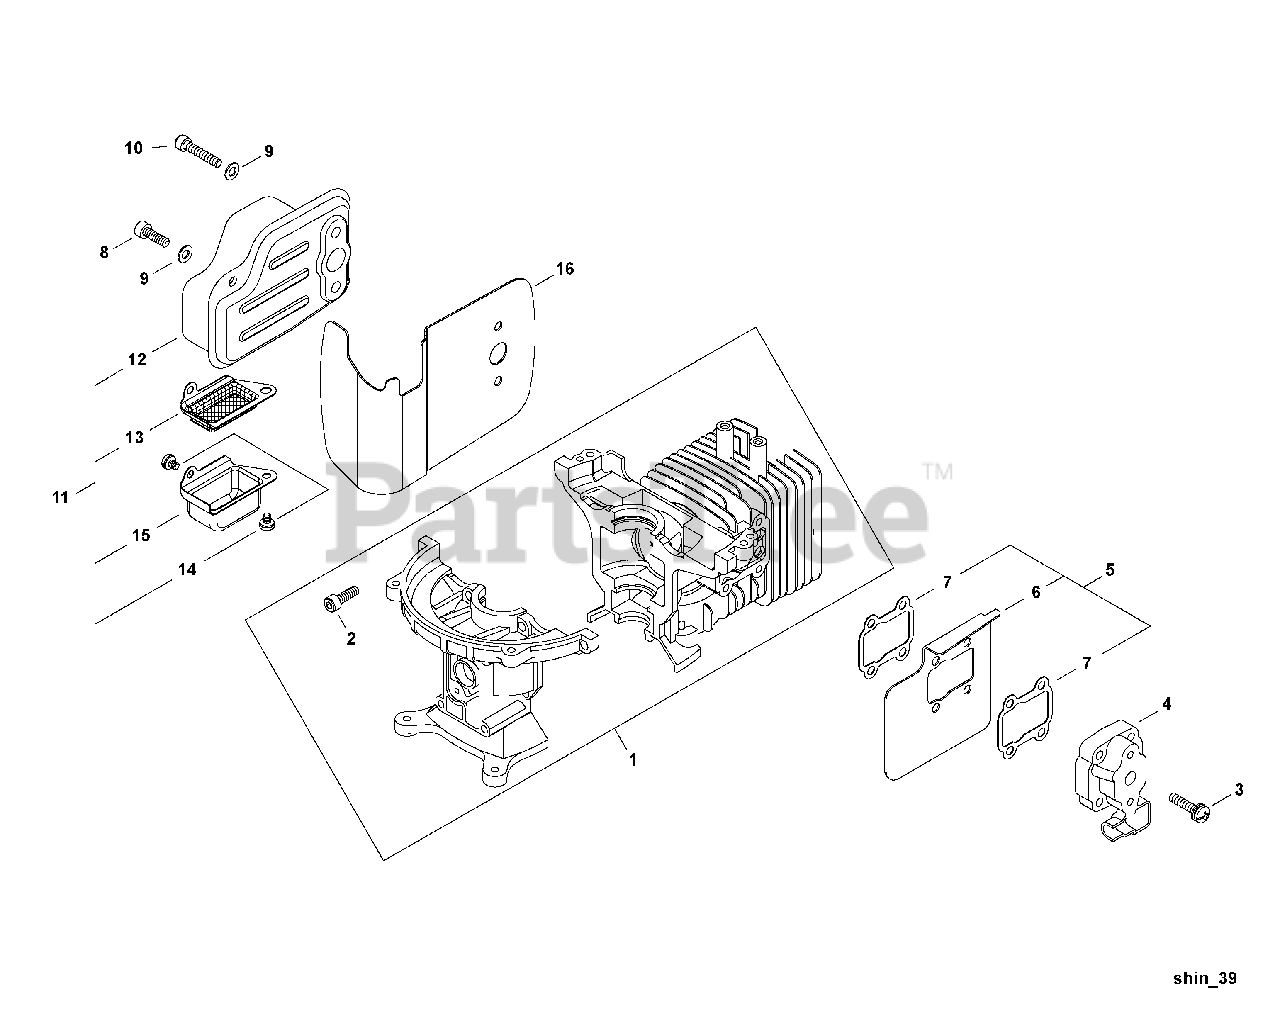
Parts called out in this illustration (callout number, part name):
1	CYLINDER & CRANKCASE ASSY
2	BOLT 5×16
3	SCREW M5×22
4	INSULATOR WITH REED VALVE
5	SHIELD ASSY, INTAKE HEAT
6	HEAT SHIELD, INTAKE
7	GASKET, EXHAUST
8	BOLT 5×16
9	WASHER, FLAT 5.5×10×0.8
10	BOLT M5×25
11	MUFFLER ASSY
12	MUFFLER
13	SCREEN, SPARK ARRESTER
14	SCREW M4×6
15	GUIDE, EXHAUST
16	HEAT SHIELD, EXHAUST
